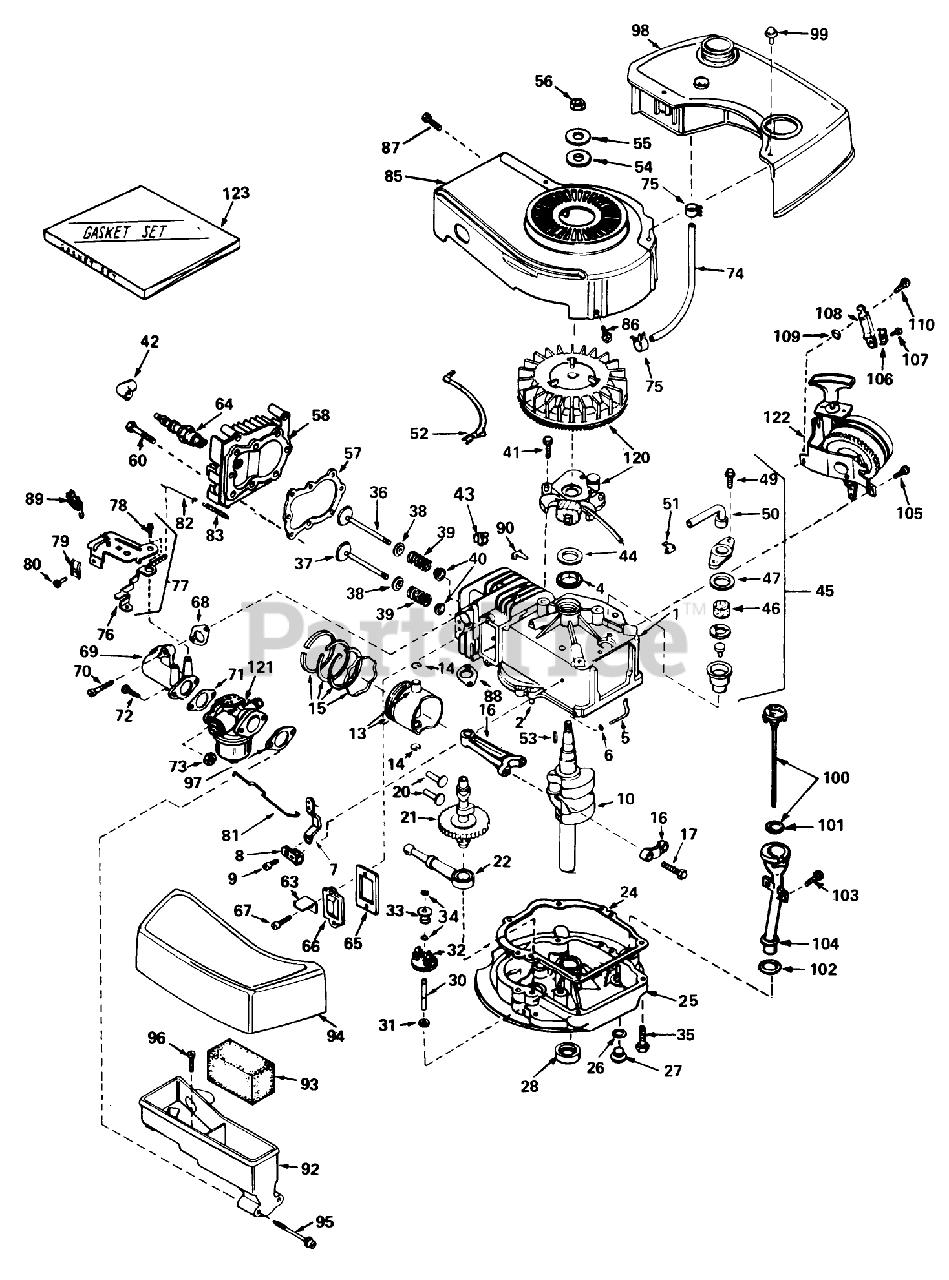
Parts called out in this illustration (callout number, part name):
1	Cylinder Assy. (Incl. Ref. #2, 4 105)
2	Pin-Dowel
4	OIL SEAL
5	Rod, Governor (Incl. No. 36)
6	Washer-Flat
7	Governor Lever
8	Clamp-Lever, Governor
9	Screw
10	Crankshaft
13	Piston, Pin Ring Assy. (Incl.Ref. #14 15)(Std.)
13	Piston, Pin Ring Assy. (Incl. #14 15)(.010 oversize)
13	Piston, Pin Ring Assy. (Incl.Ref. #14 15) (.020 oversize)
14	Ring-Retaining, Piston Pin
15	Ring Set Piston (Std.)
15	Ring Set Piston (.010 Oversize)
15	Ring Set Piston (.020 Oversize)
16	Rod Assy., Connecting (Incl. Ref. #17)
17	Bolt-Rod, Connecting
20	Lifter-Valve
21	Camshaft(Mech.Comp. Release)
22	Oil Pump ASM
24	Gasket, Mounting
25	Flange Assy., Mounting (Incl. Ref. #26thru 30)
26	Gasket-Oil Drain
27	Plug Oil Drain
28	Seal Oil
30	Shaft-Governor
31	Washer-Flat
32	Governor Gear ASM
33	Spool-Governor
34	Ring-Retaining
35	Screw (1/4-20 x 1-1/4)
36	Valve, Intake (Incl. Ref. #38, 39 40) (Std.)
36	Valve, Exhaust (1/32" Oversize) (Incl. Nos. 8, 9 10)
37	Valve, Exhaust (Standard) (Incl. Nos. 8, 9 10)
37	Valve, Exhaust (1/32" Oversize) (Incl. Nos. 8, 9 10)
38	Cap-Upper Valve Spring
39	Spring-Valve
40	Cap-Valve, Spring
41	Screw
42	Cover-Spark Plug
43	51004 GIL ROTARY TI
44	Gasket Stator
45	Breather Assy. (Incl. Ref. #46, 47, 49, 50 51 )
46	Element-Breather
47	Gasket-Breather
49	Screw, Hex Hd. w/Conical
50	Tube, Breaker
51	Clip, Breather
52	Wire Ground
53	Key-Flywheel
54	Washer Flat
55	Washer-Spring
56	Hex Nut
57	63573 GIL 42 SNWTHW
58	Head-Cylinder
60	Screw (5/16-18x1-1/2)
63	Retainer Clip
64	Plug, Spark (J17LM or equiv.)
64	Plug, Spark (Champion RCJ-8)
65	Gasket-Breather
66	Cover-Valve
67	Screw
68	Gasket, Intake
69	Pipe, Intake
70	Screw (1/4-20 x 1)
71	Gasket-Carburetor
73	Nut and Lock Washer (1/4-28)
74	Line-Fuel
75	Clamp-Line, Fuel
76	Lever Control
77	Control Assy., Speed (Incl. Nos, 76, 78 89)
78	Screw, Hex Washer Hd Shoulder Self-Tap
79	Conduit
80	Screw (10-32 x 3/8)
81	Link-Throttle
82	Link Governor Spring
83	Spring Governor
85	Housing Blower
86	Screw
87	Screw (10-24 x 9/16)
88	Gasket Exhaust
89	Terminal
90	Clip-Wire
92	Body Air Cleaner
93	Filer, Air
94	Cove, Air Cleaner
95	Screw Fil Hd.
96	Screw, Hex Hd.
97	Gasket-Air Cleaner
98	Tank, Fuel
99	Screw (10-32 x 35/64)
100	Dipstick, Oil (Incl. Ref. #101)(Twist Lock)
101	O-Ring
102	Gasket
103	Screw (10-32 x 1/2)
104	Tube-Oil Fill
105	Screw (1/4-20 x 1/2)
106	Conduit
107	Screw (10-32 x 3/8)
108	Bracker
109	Washer
110	Screw (1/4-20 X 5/8)
120	Magneto
121	Carburetor (Incl. Ref. #71 )
122	Starter
123	53024/VAR.16HP O/P
